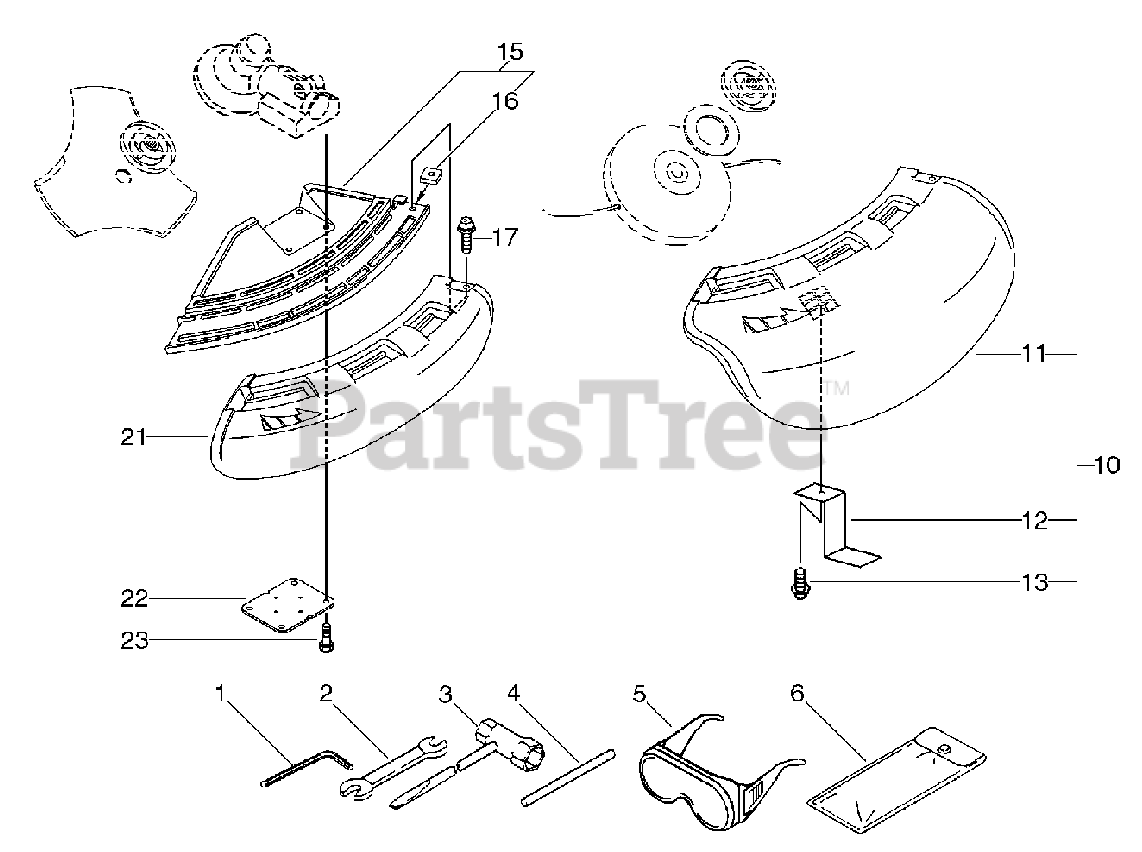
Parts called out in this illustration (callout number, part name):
1	HEX KEY - 4mm
2	SPANNER - 8X10mm
3	T-WRENCH - 17X19mm
4	LOCKING TOOL
5	GOGGLES
6	BAG, TOOL
10	DEBRIS SHIELD KIT - TRIMMER
11	SHIELD, DEBRIS - TRIMMER
12	KNIFE, TRIMMER LINE
13	SCREW - 5X12
15	ADAPTOR, DEBRIS SHIELD
16	NUT
17	SCREW - 5X18
21	SHIELD, DEBRIS - BLADE
22	BRACKET, SHIELD
23	SCREW - 5X25
